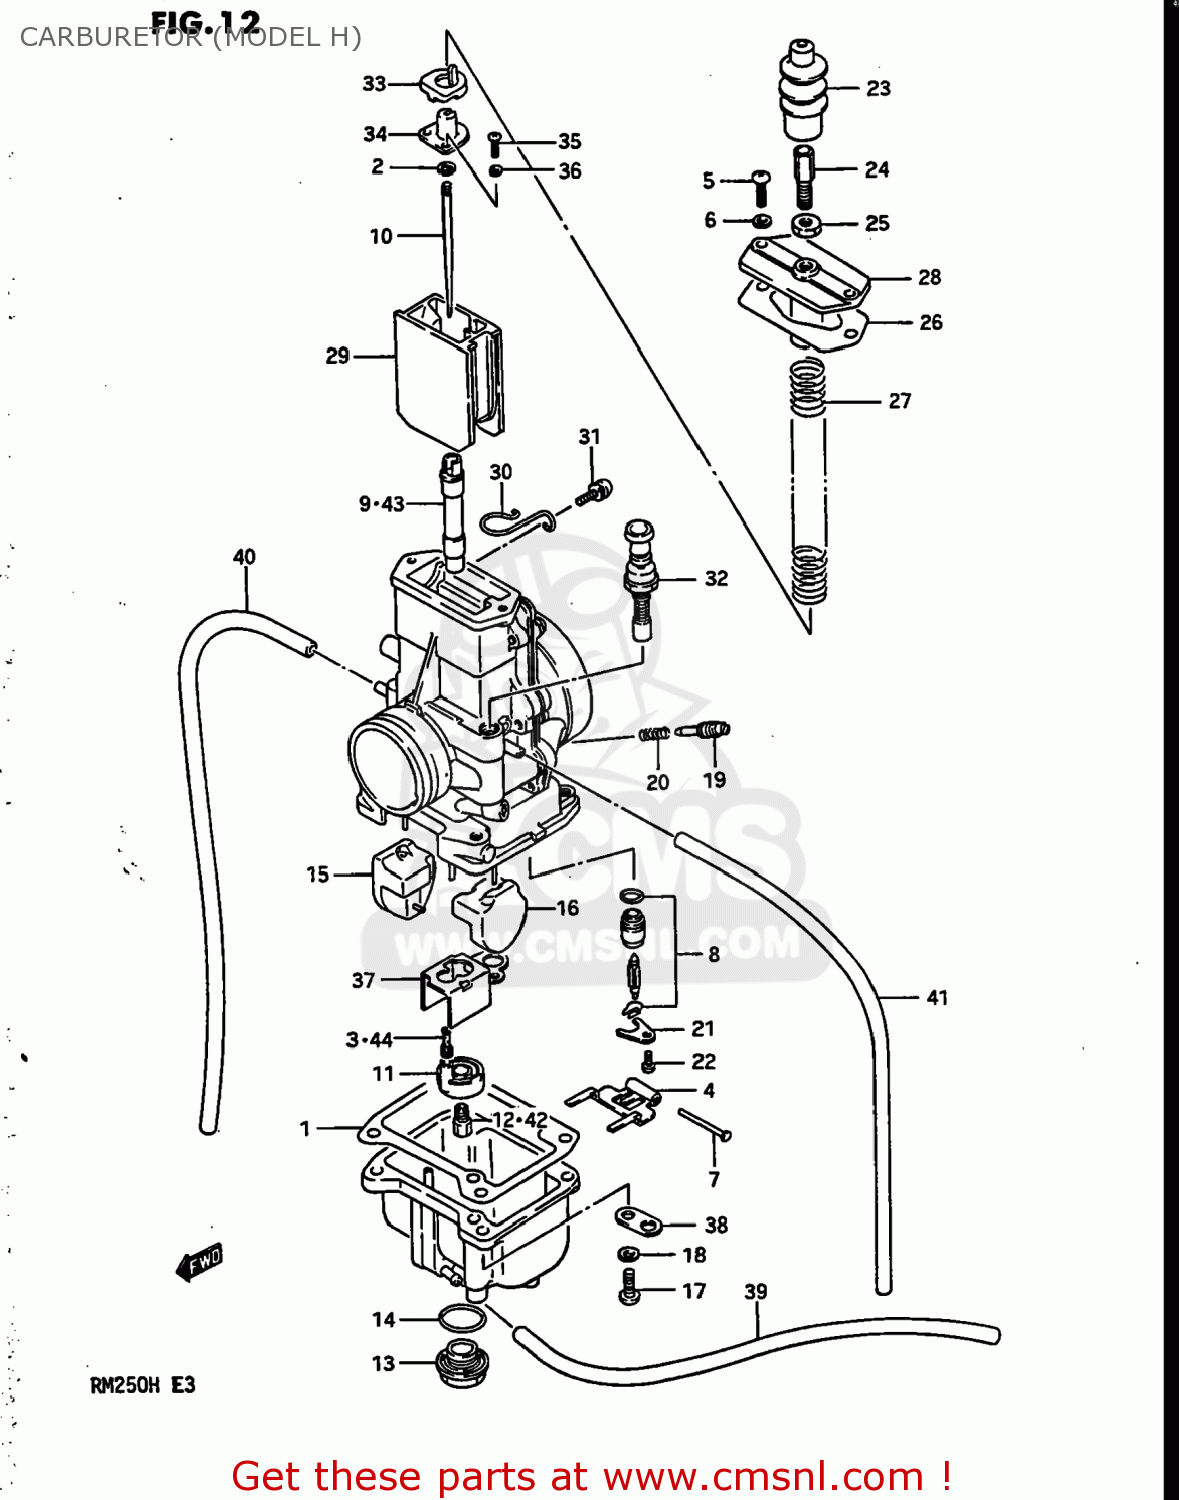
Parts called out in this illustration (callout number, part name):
1	GASKET,FLOAT CAHMBER (NAS)
2	CLIP,NEEDLE
3	JET,PILOT(35)
4	ARM,FLOAT
5	SCREW
6	LOCK WASHER
7	PIN,FLOAT
8	VALVE ASSY,NEEDLE
9	JET,NEEDLE
10	NEEDLE JET
11	RING
12	JET,MAIN(350)
13	SCREW,GUIDE
14	O RING,DRAIN PLUG
15	FLOAT,R
16	FLOAT,L
17	SCREW
18	LOCK WASHER
19	SCREW,PILOT AIR
20	SPRING
21	PLATE
22	SCREW
23	CAP,CABLE ADJUSTER
24	ADJUSTER,CABLE
25	NUT
26	GASKET,MIXING CHAMBER (NAS)
27	SPRING
28	CAP,CARBURETOR,TOP
29	VALVE
30	CLIP
31	SCREW
32	PLUNGER ASSEMBLY
33	SEAT,RETURN SPRING
34	PLATE,NEEDLE JET
35	SCREW
36	LOCK WASHER
37	PLATE
38	PLATE
39	HOSE
40	HOSE
41	HOSE
42	JET,MAIN(310)
43	JET,NEEDLE
44	JET
